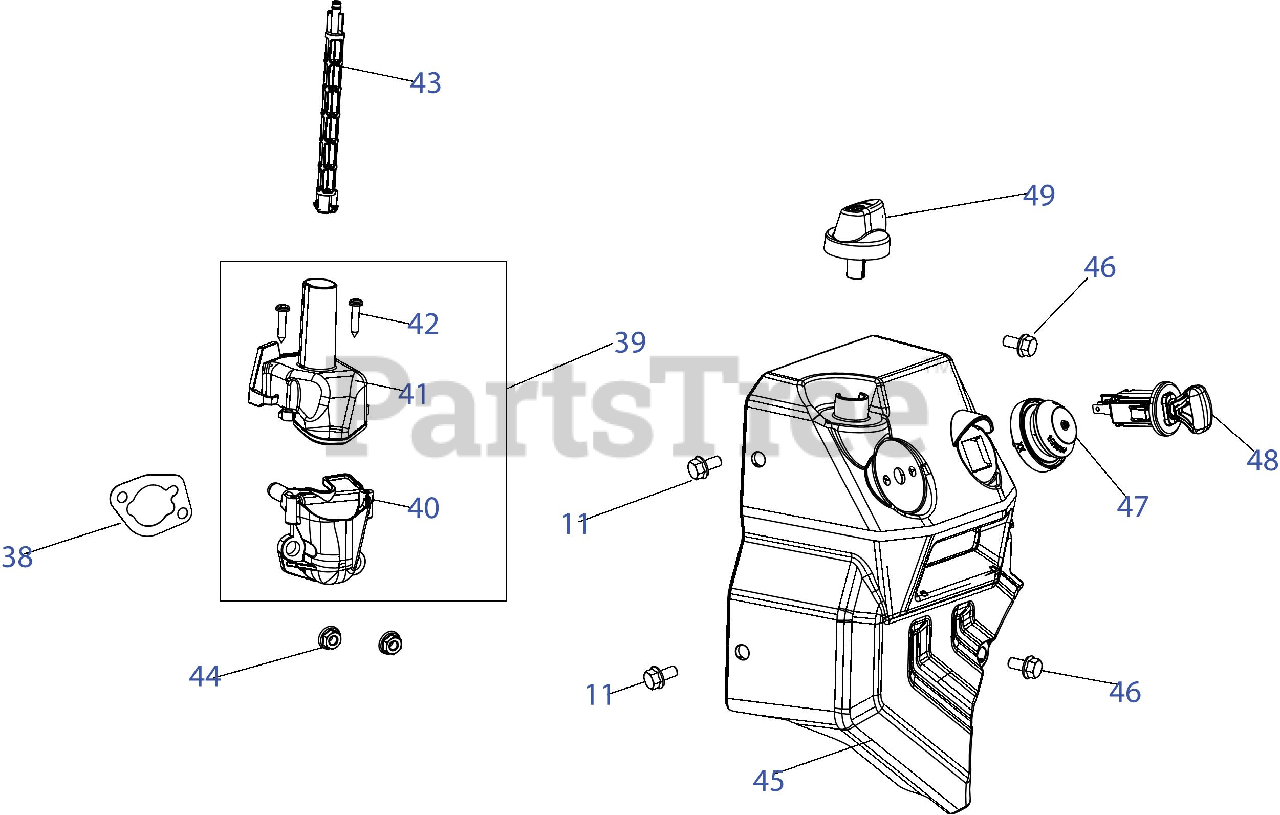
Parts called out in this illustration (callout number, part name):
11	Bolt, M6?12
38	Gasket, Air Filter
39	Heater Box
40	Air Filter Base
41	Upper Cover, Heater Box
42	Self-tappling Screw, ST4.2?16
43	Choke Linkage
44	Nut, M6
45	Control Panel
46	Bolt, M6?18
48	Stop Switch
49	Choke Lever
115	Stop Switch Key
